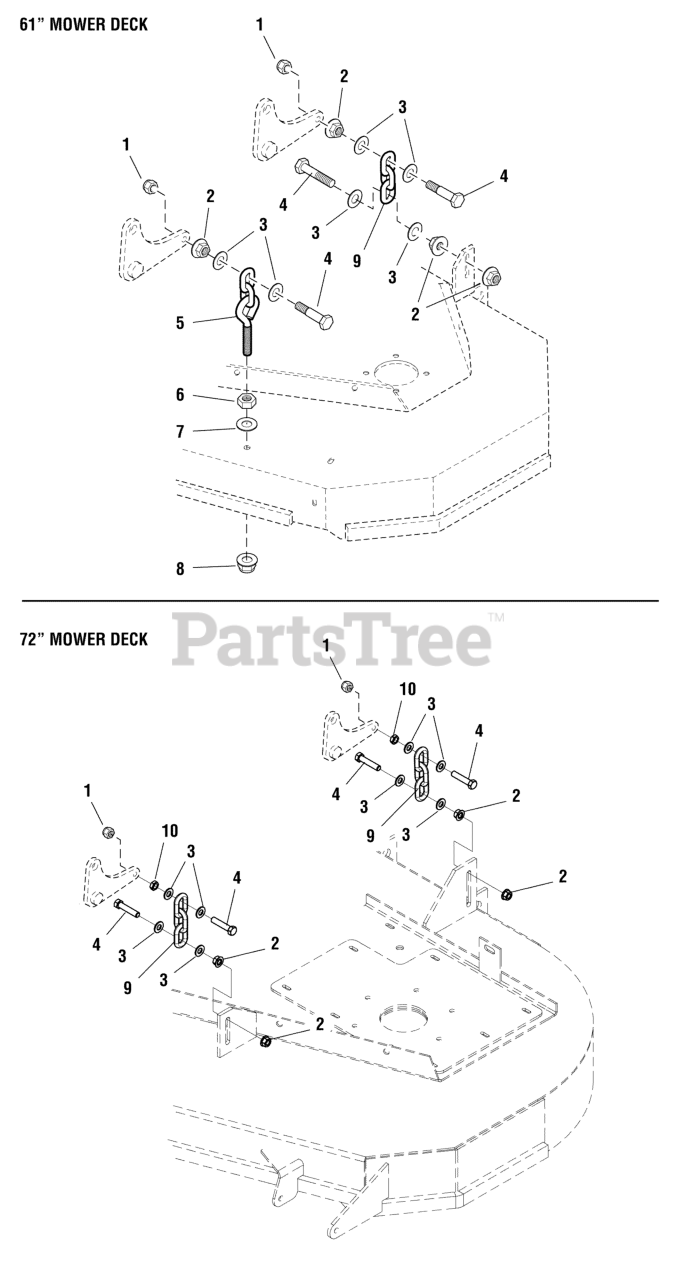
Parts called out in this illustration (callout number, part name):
1	NUT, 3/8-16 HEX SIDE LOCK
2	NUT, 3/8-16 HEX SERRATED FLANGE
3	WASHER, 3/8 SAE
4	BOLT, 3/8-16 X 1-3/4" GD5 CZ
5	HANGER, FRONT DECK-2LINK, 5.5" EB
6	NUT, 1/2-13 HEX
7	WASHER, 1/2 SAE
8	NUT, Hex Flange, Nylock, 1/2-13
9	CHAIN, 5/16 GD30, 3 LINKS
10	NUT, 3/8-16 HEX SIDE LOCK
